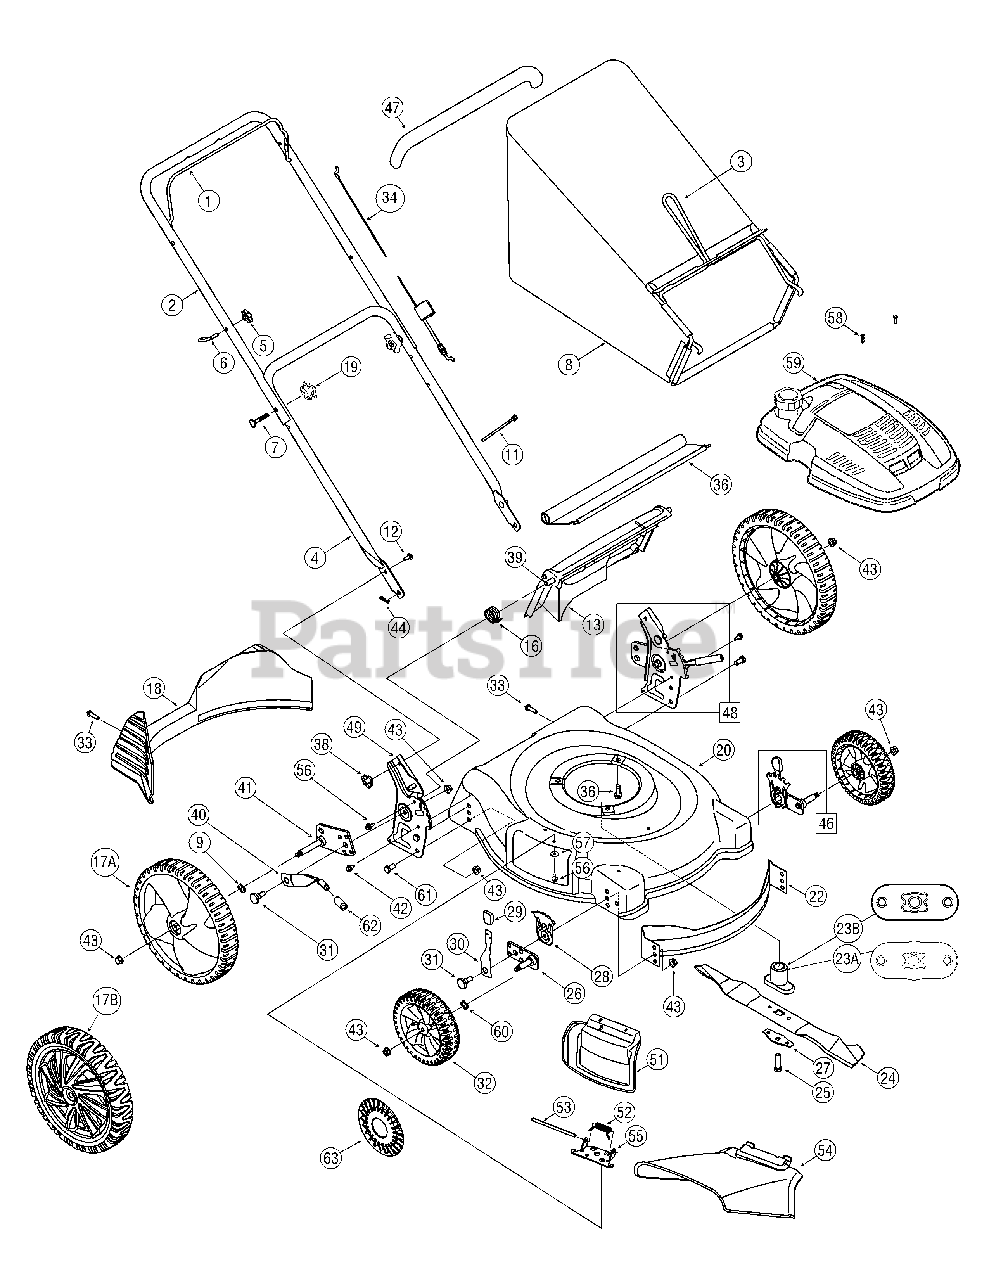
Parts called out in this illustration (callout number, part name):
1	Blade Control Handle - Black
2	Upper Handle - Black
3	Catcher Lower Frame
6	Rope Guide Bolt
7	Curved Carriage Bolt 5/16-18 x 2.00
8	Generic Grasscatcher Bag - Black
9	Spring Wash. .5 x 1.0 (w/2" side rear wheels)
10	Hex Cap Screw1/4-20 x 1.5" Lg.
11	Cable Tie
12	Carriage Bolt 1/4-20 x .75 Gr. 1
13	RB Chute Door
16	RH Torsion Spring
17A	Not used in this application
17B	Wheel Ass'y Comp.12 x 2.125 Idle Zag Grey
19	Knob - Star 5/16-18
20	21" Deck Ass’y (w/ side discharge)
22	Front Baf fle 21"
23A	Blade Adapter 25 mm x 2.15 (w/star)
23B	Not used in this application
24	21" Mulching Blade (w/star)
25	Hex Bolt 3/8-24 x 2.5" Lg. Gr. 8
27	Blade Bell Support
28	Height Adjuster Plate
29	Knob
30	Spring Lever Ass’y
31	Shoulder Screw .50 Dia. x .385
32	Wheel Ass'y 8 x 2.125 Idle Zab BB
33	Hex. L-Scr. 1/4-15 x 1.0
34	Control Cable 40.0" Lg. (w/Honda & B&S)
37	Flange Locknut 1/4-20
38	Wingnut 1/4-20
40	Spring Lever SP (w/o knob)
41	Pivot Bar RH SP
42	Hex HD. TT Tap Scr. 1/4-20 x 5/8
43	Flange Locknut 3/8-16
44	Int. Cotter Pin 5/16 DIA
45	Hex Wash HD Tap Scr 3/8-16 x .88
46	Height Adj. Ass’y LH (w/8" Front Wheels)
46	Height Adj. Ass’y RH (w/8" Front Wheels)
47	Snap-On Bail Cover - Grey
48	LH Rear Height Adj. Ass’y Complete
48	RH Rear Height Adj. Ass’y Complete
49	LH Height Adj. Brkt.
49	RH Height Adj. Brkt.
50	Spring Washer .50 ID x 1.0 OD x .022
51	Complete Hinged Mulching Plug Ass'y
52	Torsion Spring
53	Hinge Pin
54	Chute Deflector
55	Chute Adapter
56	Hex Wash S-Tapp Scr 1/4-20 x .50
57	Cupped Washer .265 ID x .75 OD x .062
58	Screw
59	Shroud (w/MTD Engine)
60	Wave Washer .510 x .750 x .017
61	Hex Hd. Cap Screw 3/8-16 x .75
63	Hub Cap - Grey w/snaps
